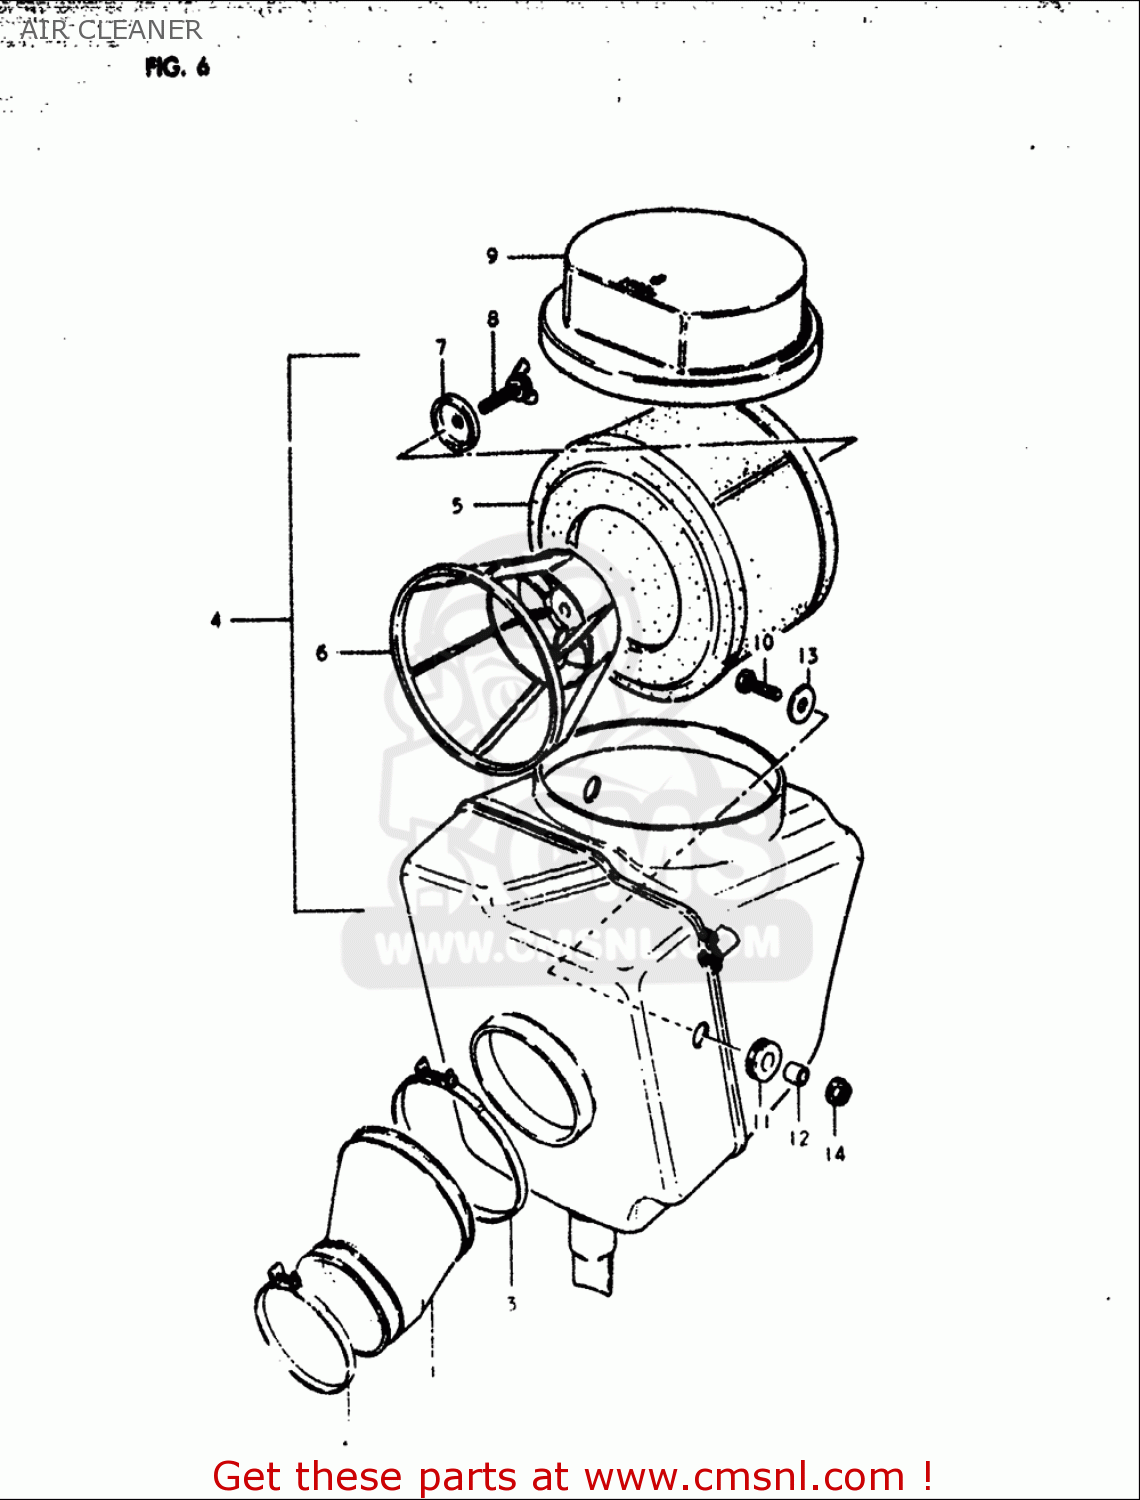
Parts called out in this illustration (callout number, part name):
1	TUBE,AIR CLEANER OUTLET
2	CLAMP
3	CLAMP
5	FILTER
6	HOLDER
7	WASHER,AIR CLEANER
8	BOLT
10	BOLT
11	CUSHION
12	SPACER(6.5X9X9)
13	WASHER(6.5X20X1.2)
14	NUT
